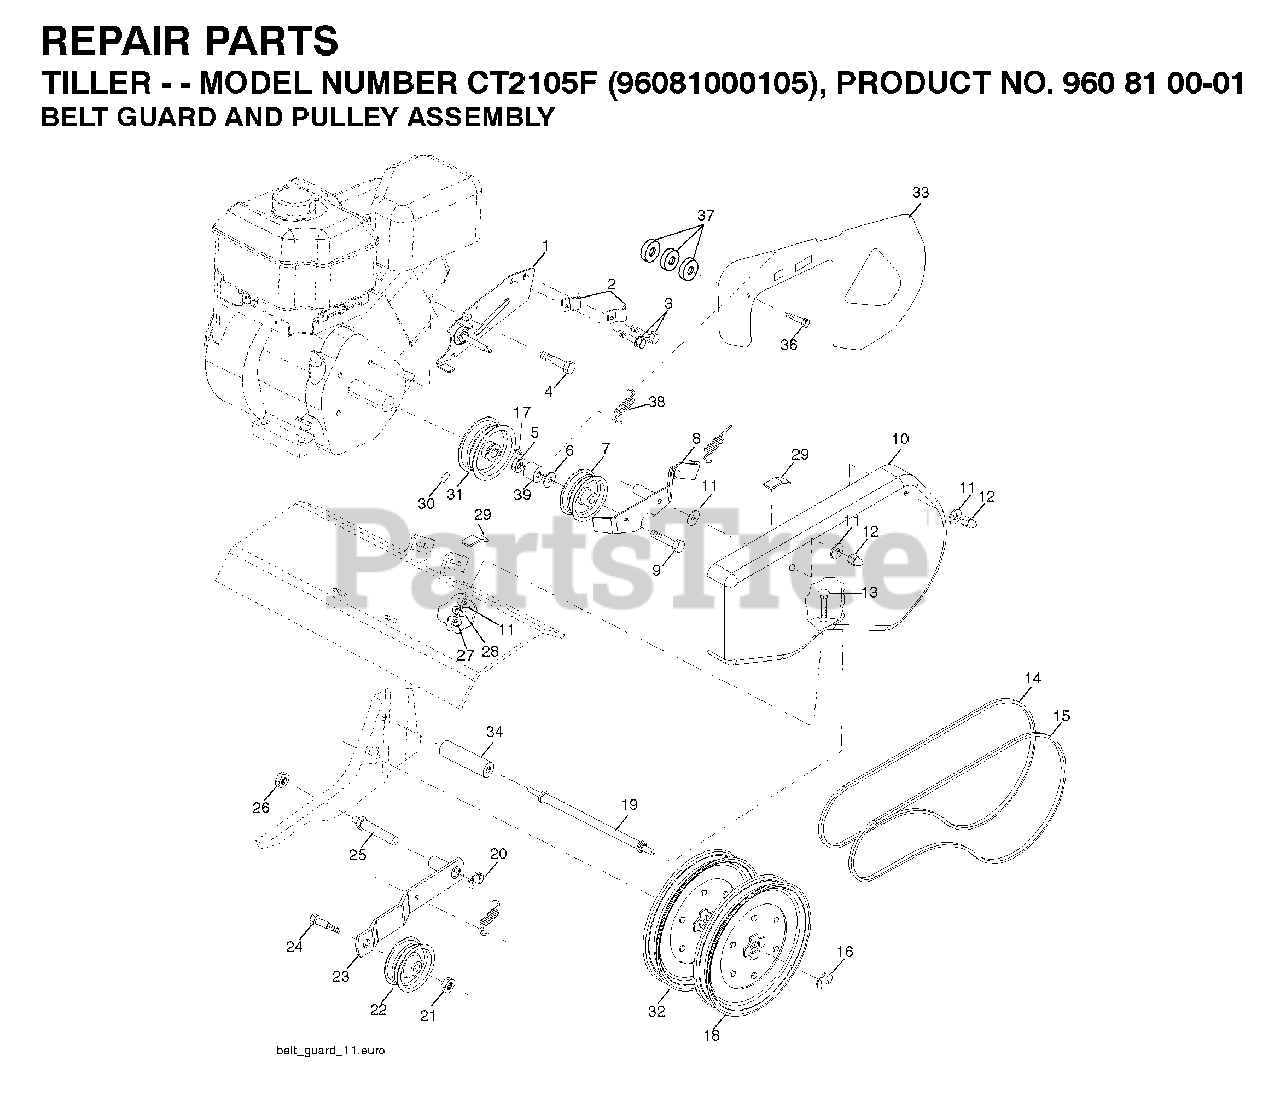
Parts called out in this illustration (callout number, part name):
1	RP BRKT.ASM.GUARD.BELT
2	CONDUIT CLIP T
3	TAPPING SCREW
5	LOCKNUT
7	PULLEY
8	ARM
9	BOLT
11	WASHER
12	CAP
15	BELT
16	RETAINING RING LT
18	SHEAVE,TRANS."D"
19	BOLT.BELT.GUARD
20	KLIP RING TI
21	NUT
22	PULLEY, IDLER
23	ARM, IDLER
25	SHAFT.IDLER.TILLER
26	JAM NUT TI
27	NUT
28	LOCKWASHER
29	PAD IDLER TI
32	SHEAVE.TRANS
37	WASHER
38	SPRING.EXTENSION
